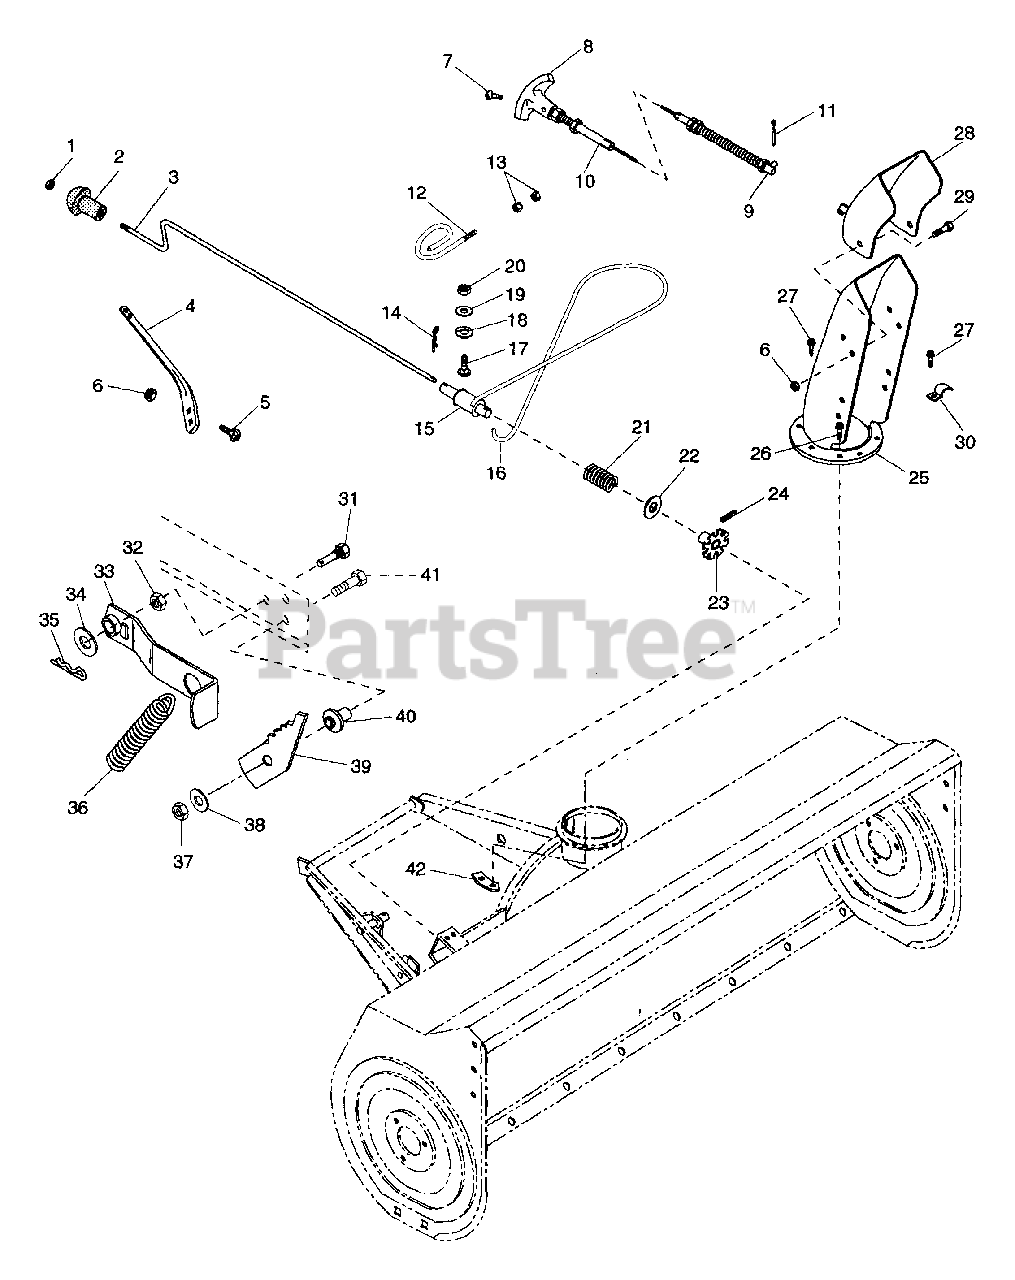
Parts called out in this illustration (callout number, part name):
1	NUT-LK-JAM-CTR .375-16 PL
3	CHUTE CONTROL CRANK
4	CHUTE SUPPORT
5	BLT-RDHDSQNK .38-16X1.0 PL
6	NUT-LK-CTR .375-16 GR A PL
7	SCR-MCH 8-32X.75 SLPAN PL
8	KNOB-BLACK
10	CONTROL CABLE
11	PIN-COTR .09X.75 PL
12	CABLE SUPPORT
13	NUT-LK-FLG .250-20 PL
14	PIN-HAIR INT .08X.38X1.42 YWZC
15	SPOOL
17	BLT-RDHDSQNK .25-20X.75 GR5PL
18	WSHR-FL-STL.281X.62X.065 PL
19	WSHR-LK .313X.062
20	NUT-HEX .250-20 PL
21	SG-COMP .054X.75X1.6
22	WSHR-FL-STL .640X1.005X.062 PL
23	DISC ASSEMBLY
24	PIN-ROLL .188X1.00
25	DISCHARGE CHUTE
26	SCR-TAP 12-24X.50 TORX YWZC TR
27	SCR-TAP 12-24X.75 HWH PL TR
28	DEFLECTOR W/DECAL
29	BLT-HEX .38-16X.75 PL GR2
30	CABLE CLAMP
31	STUD-WEIGHT
32	NUT-LK-CTR .50-13
33	SPRING ARM
34	WSHR-FL-STL .458X.750X.06 PL
35	PIN-HAIR INT .08X.18X1.18
36	SG-TENS .188X1.50X8.5 WLD 57
37	NUT-LK .312-18 GR A PL
38	WSHR-FL-STL .38X.875X.083 PL
39	SPRING ASSIST CONTROL
40	SPACER .323X.498X.531X1.000
41	BLT-HEX .31-18X1.25 PL GR2
42	CHUTE CLAMP
